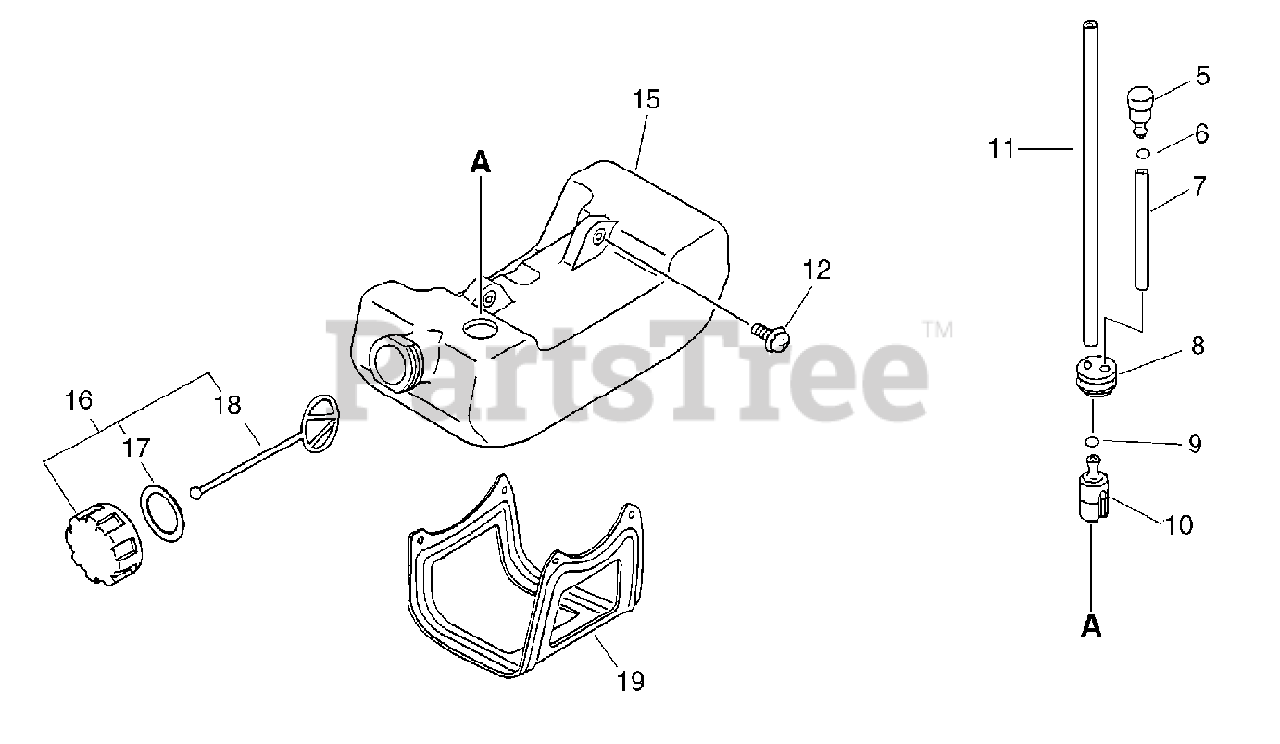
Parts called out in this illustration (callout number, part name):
5	Valve, Check
8	Grommet
10	Strainer, Fuel
12	Screw 5*16
15	Tank, Fuel
16	Cap Assy, Fuel
17	Gasket, Fuel Cap
18	Connector, Cap
19	Stand (BL)
